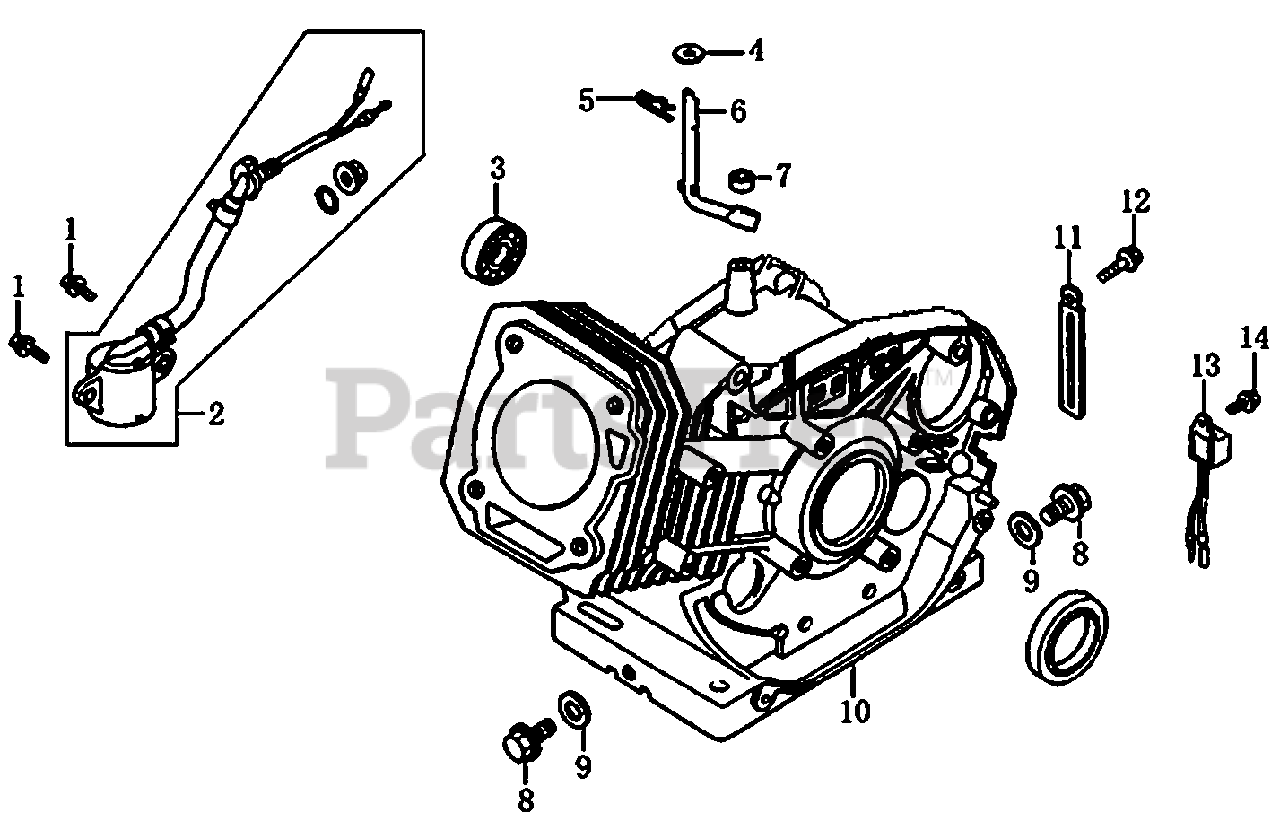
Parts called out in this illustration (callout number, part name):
1	BOLT, FLANGE, 6×14
2	SWITCH ASSY., OIL LEVEL
3	BEARING, RADIAL BALL, 6202
4	WASHER,8x16x1.2
5	PIN, LOCK, 10MM
6	SHAFT, GOVERNOR ARM
7	OIL SEAL, 8×14×4
8	BOLT, DRAIN PLUG
10	CRANKCASE
12	BOLT, FLANGE, 6×12
13	ALERT UNIT,OIL
14	BOLT, FLANGE, 6×12
